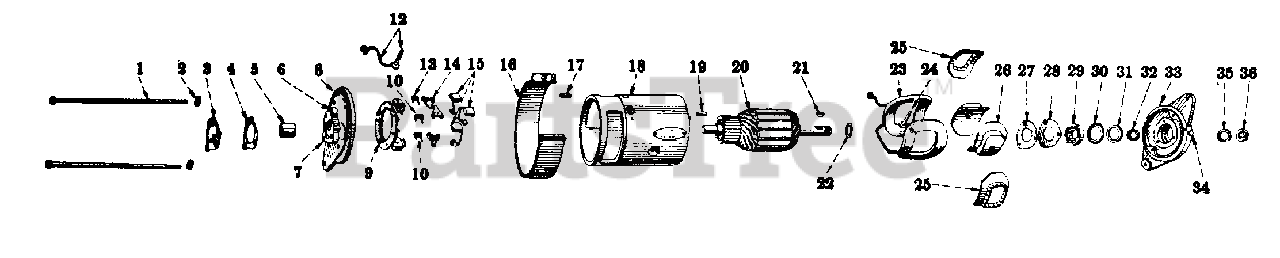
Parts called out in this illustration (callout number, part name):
2	WASHER, 5/16 C-Z HEAVY LOCK
3	PLATE, COMMUTATOR END FRAME COVER
4	GASKET, COVER PLATE
5	BUSHING, COMMUTATOR END
6	OILER, COMMUTATOR END FRAME
7	PLUG, COMMUTATOR END OILER WICK
8	FRAME ASSY, COMMUTATOR END
9	PLATE W/THREE HOLDERS, BRUSH
10	SPRING, MAIN BRUSH
12	POLE, ARMATURE TERMINAL
13	SPRING, THIRD BRUSH
14	HOLDER, BRUSH
15	BRUSH, THIRD
16	BAND, COVER W/NUT IH-120614 AND SCREW, IH-132926
17	PIN, COMMUTATOR END FRAME DOWEL
18	FRAME
19	PIN, DRIVE END FRAME DOWEL
20	ARMATURE
21	KEY, 1/8 X 5/8 WOODRUFF NO. 5 ALY-STL
22	WASHER, DRIVE END SPACE
23	COIL SET, FIELD
24	STUD, FIELD TERMINAL
25	INSULATOR, FIELD COIL
27	PLATE, BALL BEARING RETAINER
28	GASKET, BALL BEARING RETAINER PLATE
29	BEARING, BALL
30	RETAINER, DRIVE AND FELT WASHER
31	WASHER, FELT DRIVE END
32	SPACER, PULLEY
33	FRAME, DRIVE END
34	OILER, DRIVE END BEARING
35	WASHER, DRIVE END SHAFT NUT LOCK
36	NUT, DRIVE END SHAFT
